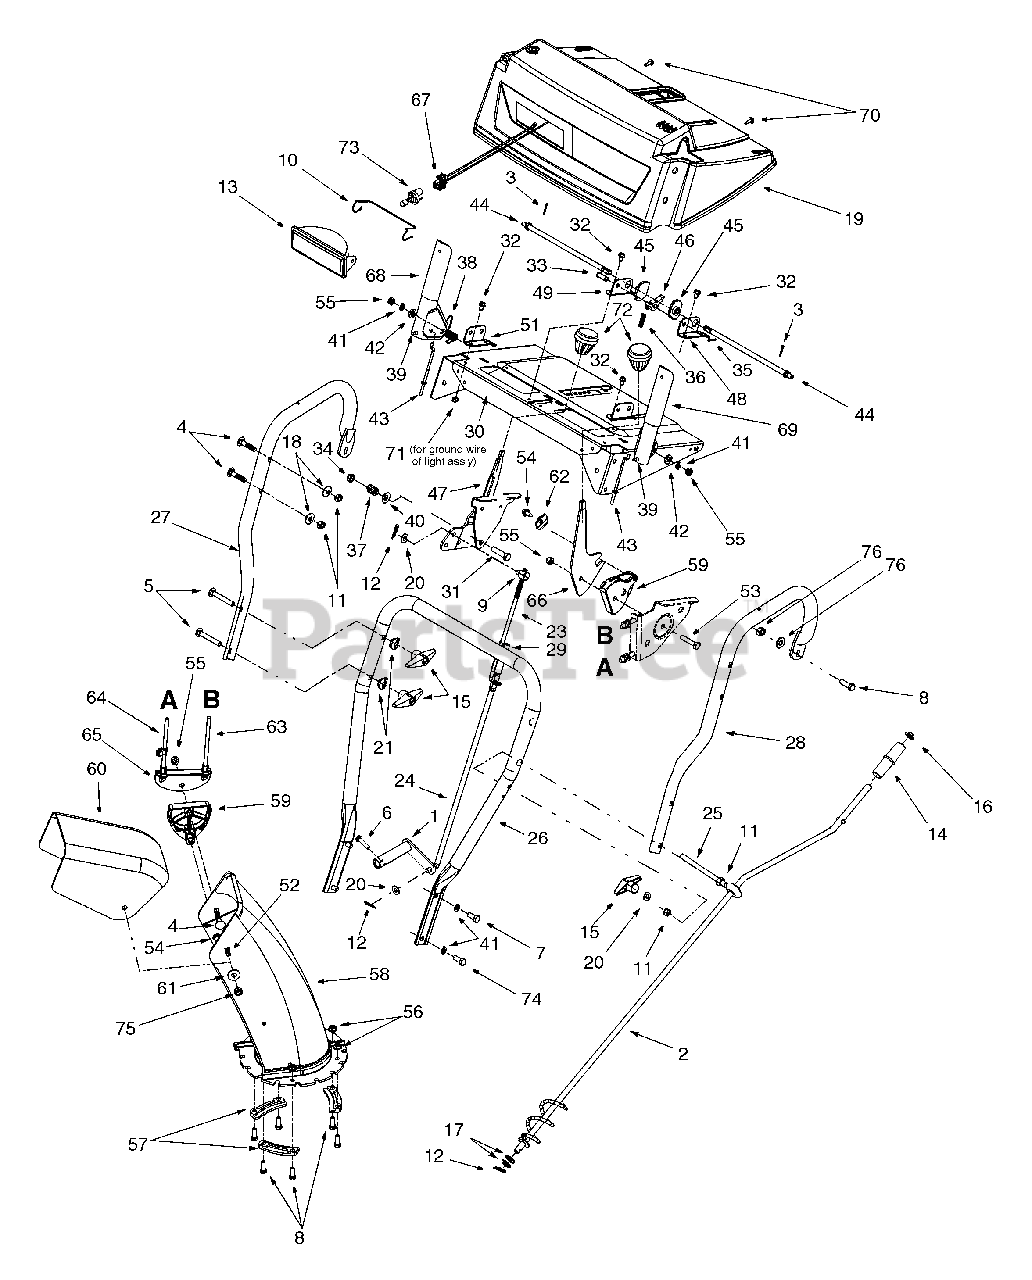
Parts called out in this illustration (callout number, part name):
2	Chute Crank Assembly
3	Cotter Pin, 3/32 x .75
4	Carriage Bolt, 5/16-18 x 1.75
5	Carriage Bolt, 5/16-18 x 2.25
6	Self Tapping Screw, 1/4-20 x 1
7	Hex Cap Screw, 5/16-18 x 1.0
8	Hex Cap Screw, 1/4-20 x .75
9	Ferrule, 5/16-18 x .312
10	Headlamp Retainer
11	Hex Nut, 5/16-18
12	Internal Cotter Pin
13	Lens Assembly / Lamp Housing
14	Chute Crank Knob
15	Wing Knob, 5/16-18
16	Push Cap, 3/8
17	Flat Washer, .375 x .738 x .063
18	Bell Washer, .34 x .872
19	Handle Panel, Black
20	Flat Washer, .344 x .688 x .065
21	Saddle Washer, .32 x .93
23	Upper Shift Rod
24	Lower Shift Rod
27	RH Handle (Upper), C-style
31	Hex Cap Screw, 3/8-24 x 1.5
32	Self Tapping Screw, 1/4-20 x .5
33	Clevis Pin
34	Jam Nut, 3/8-24
35	Cotter Pin, .072 x 1.0
36	Compression Spring, .36 x 1.0
37	Comp. Spring, .39 x .6 x .88
38	Torsion Spring, .44 x .8
39	Rubber Bumper
40	Bell Washer, .401 x .87 x .063
41	Lock Washer, 5/16
42	Special Washer, .35 x .72 x .13
43	Cable "Z" Fitting
45	Cam Handle Lock
46	Handle Lock Pawl
52	Carriage Bolt, 5/16-18 x .75
53	Hex Cap Screw, 516-18 x 1.5
54	Screw, 1/4-14 x .625
55	Hex Lock Nut, 5/16-18
56	Hex Flange Lock Nut, 1/4-20
57	Lower Chute Flange Keeper
58	Lower Chute
59	Chute Tilt Cable Guide
60	Upper Chute
61	Washer, 5/16
62	Special Washer, .28 x 1.2 x .06
63	Chute Deflector Control Cable
64	Chute Deflector Cable w/ Clip
67	Halogen Light Harness
68	RH Engagement Handle Ass'y
69	LH Engagement Handle Ass'y
70	Special Screw, #10-16 x .625
71	Hex Sems Nut, 1/4-20
72	Plastic Knob
73	Halogen Lamp, 12-volt, 27 Watt
74	Hex Cap Screw, 5/16-18 x .75
75	Hex Nut 5/16-18
76	Bell Washer, .265 x .75 x .062
